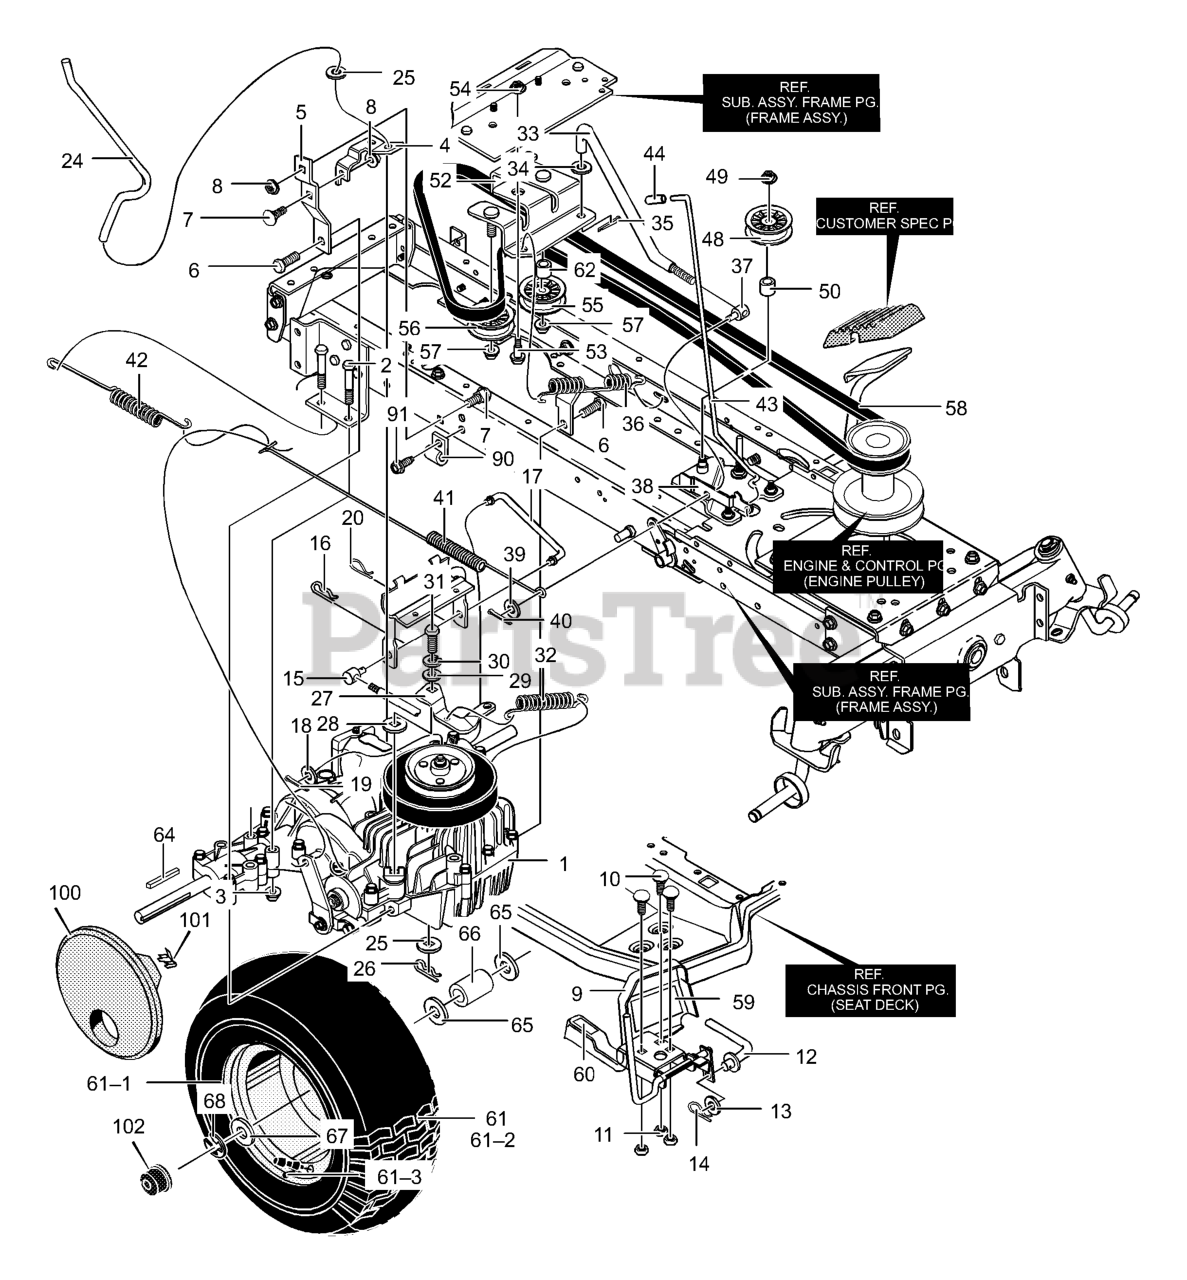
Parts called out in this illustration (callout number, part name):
1	Transaxle, Peerless **
3	NUT, 5/16-18
4	BRACKET, DISCONNECT
5	STRAP, RIGHT TORQUE
6	SCREW, 5/16-18 x 0.75
7	BOLT, CARRIAGE
8	NUT, 5/16-18 HEX
9	PEDAL ASSEMBLY, HYDRO
10	BOLT, 5/16-18X .75
11	NUT, 5/16-18 HEX
12	ROD, PEDAL LINK
13	WASHER
14	PIN, HAIR
15	ADJUST NUT
16	PIN, HAIR
17	ROD, HYDRO LINK
18	WASHER, FLAT
19	PIN, COTTER
20	PIN, HAIR
24	ROD, DISCONNECT
26	PIN, COTTER
27	ARM, DISCONNECT
29	WASHER
30	WASHER
31	SCREW, 1/4-28 X.75 NYLON
32	SPRING, EXTENSION
33	ROD, CLUTCH
35	PIN, COTTER
36	SPRING, CLUTCH
37	NUT, ADJUSTING
38	LATCH, PARK BRAKE
39	WASHER, FLAT
40	PIN, COTTER
41	SPRING, EXTENSION
42	SPRING, TENSION
43	ROD, PARKING BRAKE
48	PULLEY, IDLER
49	NUT, 3/8-16
50	SPACER 1/2 TO 17MM
52	BRACKET, IDLER
54	NUT, 3/8-16
55	PULLEY, IDLER
56	PULLEY, IDLER
57	NUT, 3/8-16
58	BELT, MOTION DRIVE
59	PAD, CONTROL PEDAL
60	PAD, TOE
61	TIRE & RIM 20X8.00-8
61-3	VALVE STEM
62	SPACER 1/2 TO 17MM
64	KEY, SQUARE
67	WASHER
70	SPACER 1/2 TO 17MM
90	RETAINER, WIRE
100	CAP, HUB
101	RETAINER
102	COVER, DUST
